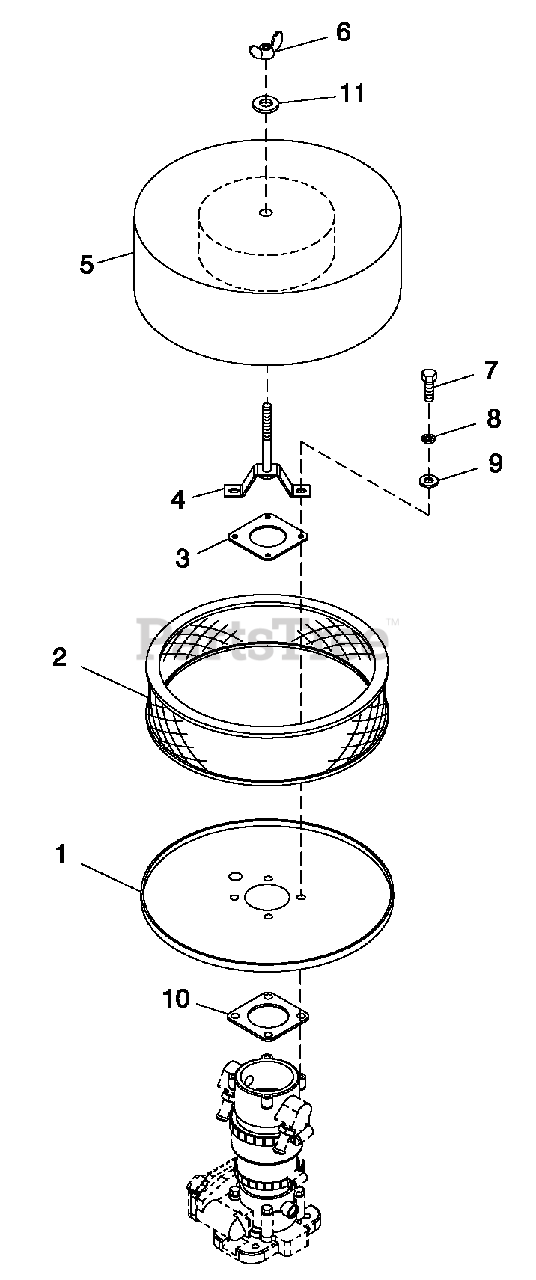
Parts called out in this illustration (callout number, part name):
1	AIR CLNR BTM PLT W/CPLR 8.1L
2	ELEMENT AIR FILTER
3	TOP PLATE VENTURI
4	HOLD DOWN AIR CLEANER PLATED
5	PLATE AIR CLEAN TOP 5.4L/6.8L
6	NUT WING 1/4-20 NYLK
7	SCREW HHC M6-1.0 X 16 G8.8
8	WASHER LOCK M6-1/4
9	WASHER FLAT M6
10	GASKET MIXER BODY
11	WASHER FLAT 1/4-M6 ZINC
